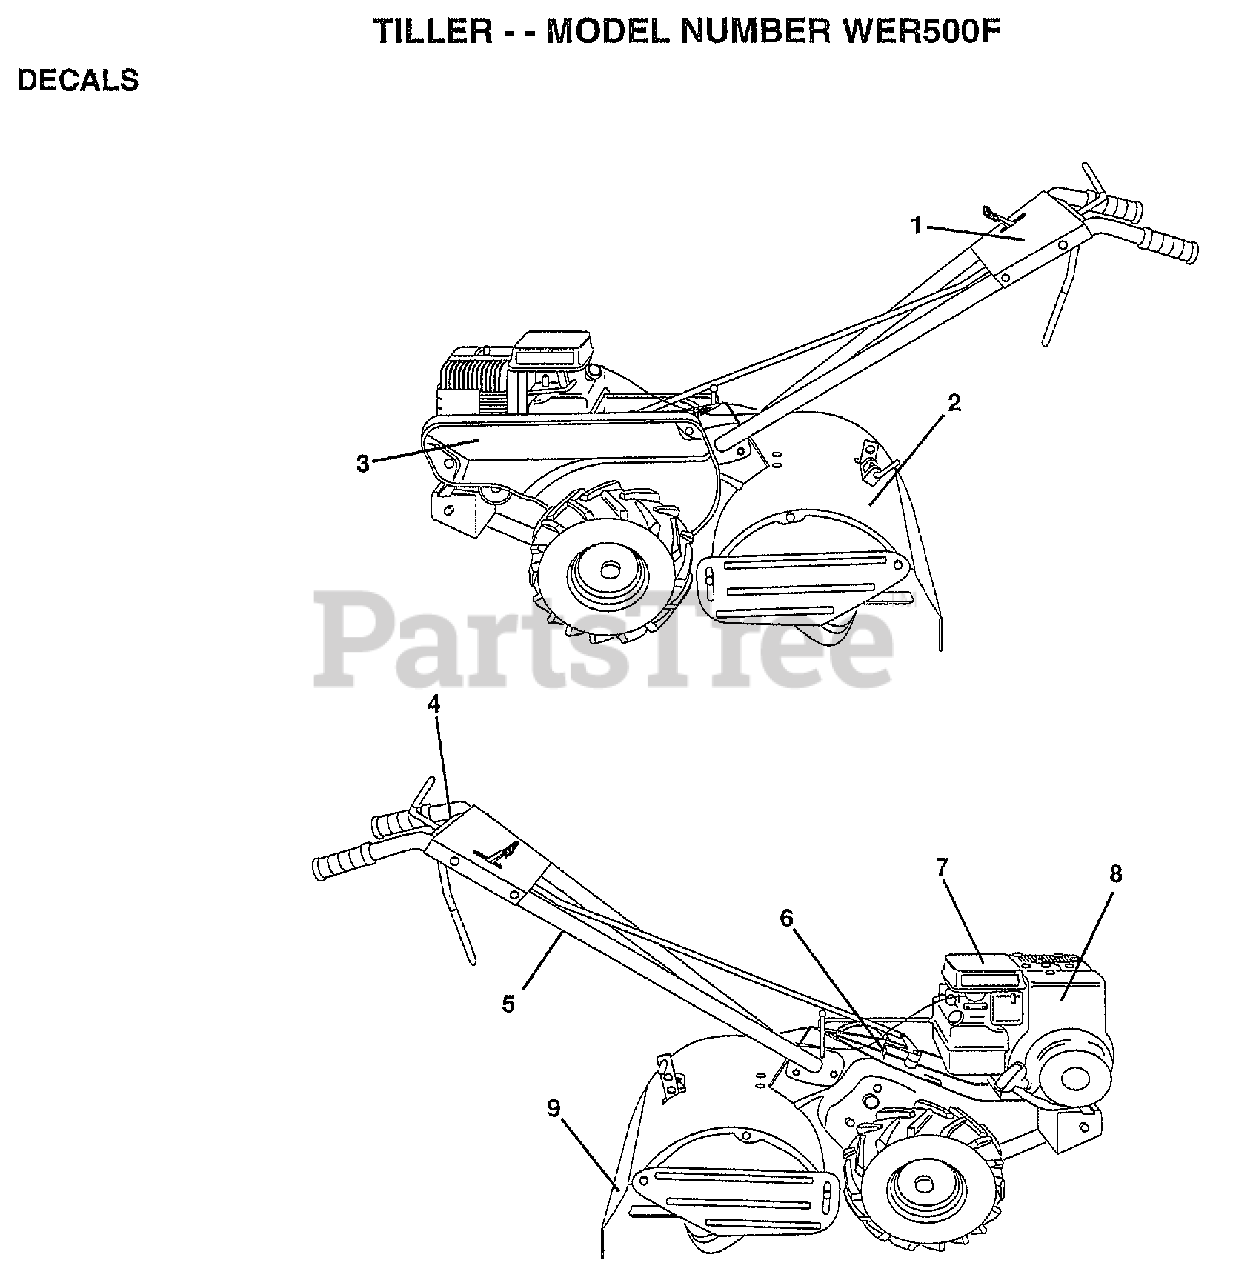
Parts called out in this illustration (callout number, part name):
1	DECAL LOGO 17 5HP
2	DECAL SHIELD TINE
3	DECAL BELT GUARD
5	DECAL TI
7	DECAL TI
8	DECAL, BRIGGS & STRATTON
